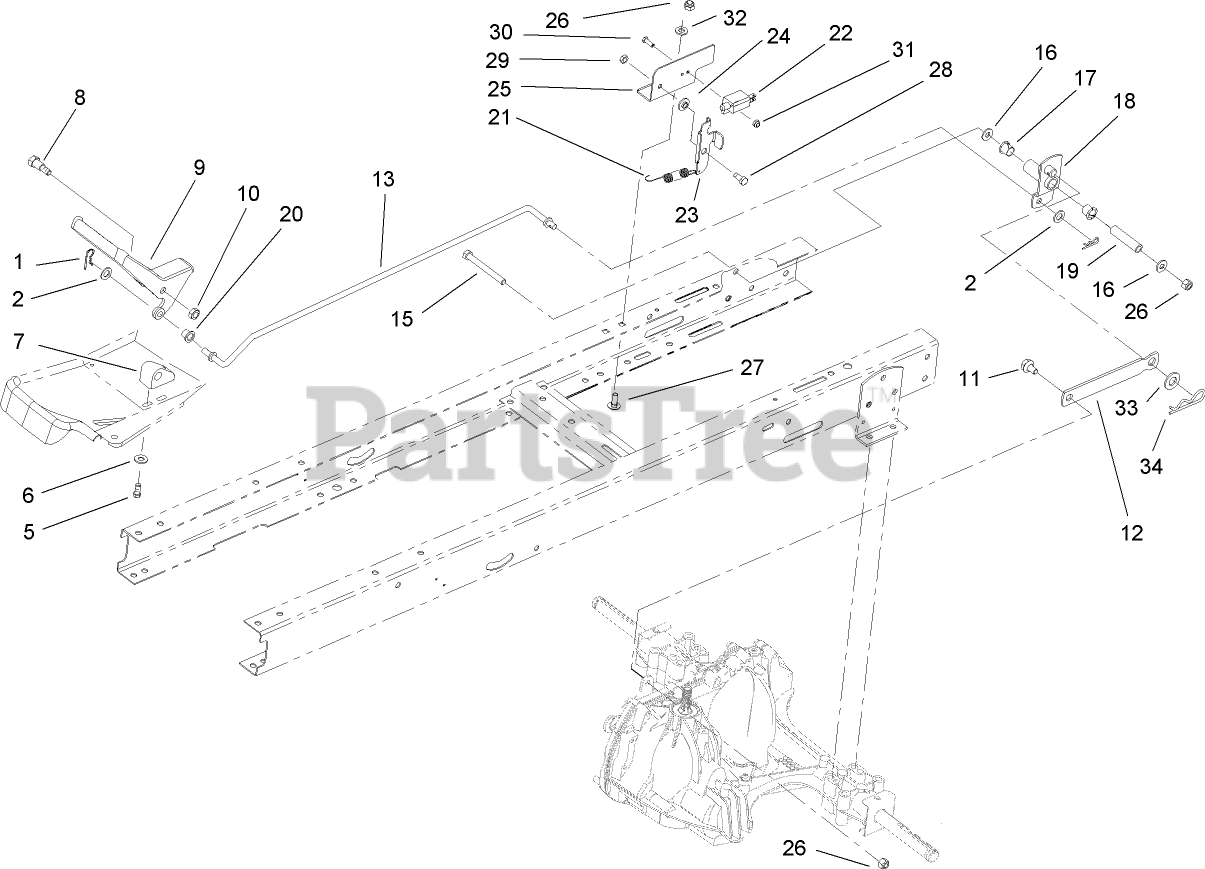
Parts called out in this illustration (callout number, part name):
2	WASHER-FLAT
5	SCREW-PLASTITE
6	WASHER-FLAT
7	BLOCK-PIVOT
8	SCREW-SHOULDER, HH
9	PEDAL-CONTROL, SPEED
11	BOLT-SHOULDER
12	LINK-CONTROL, SPEED
13	ROD-CONTROL, SPEED
15	SCREW-HH
16	WASHER-FLAT
17	BUSHING-NYLINER
18	PIVOT ASM
19	SPACER-PIVOT
20	BUSHING-FLANGED
21	SPRING-EXTENSION
22	SWITCH-POLE, SINGLE
23	BRACKET-PIVOT
24	WASHER-STEPPED
25	BRACKET-ADJUSTMENT
26	NUT-LOCK, NI
27	SCREW-CARR
28	SCREW-HHF
29	NUT-LOCK, NI
30	SCREW-SHH
31	NUT-LOCK
32	WASHER-PLAIN
33	WASHER-FLAT
34	PIN-HAIR
